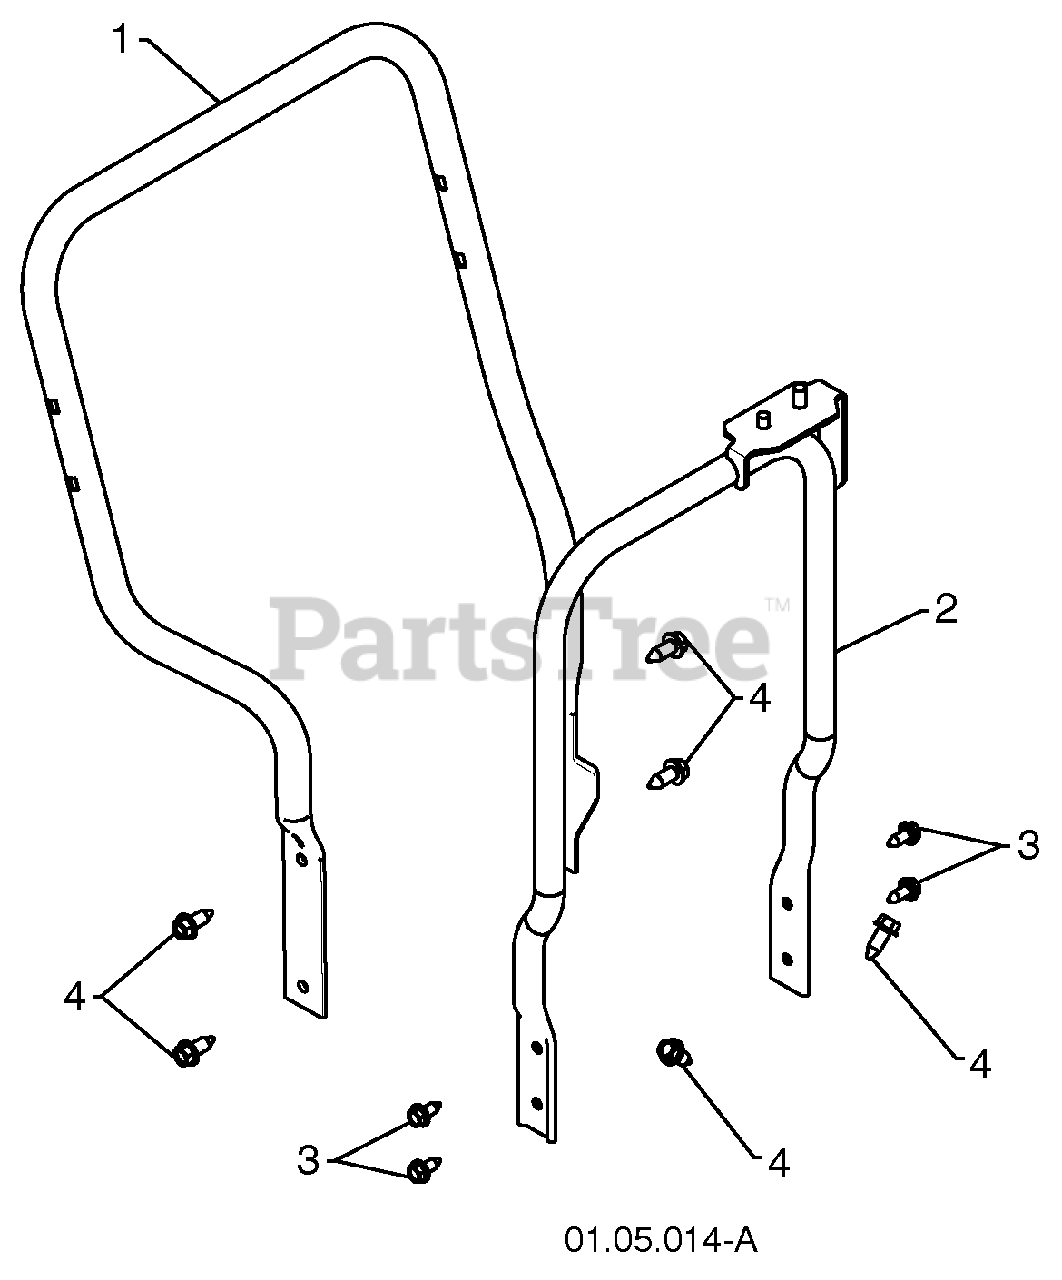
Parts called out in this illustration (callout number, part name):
1	LOWER TUBE GRAY
2	PIVOT SUPPORT
3	BOLT 5/16-18 X .750
4	SCREW 3/8-16 X 1.00
